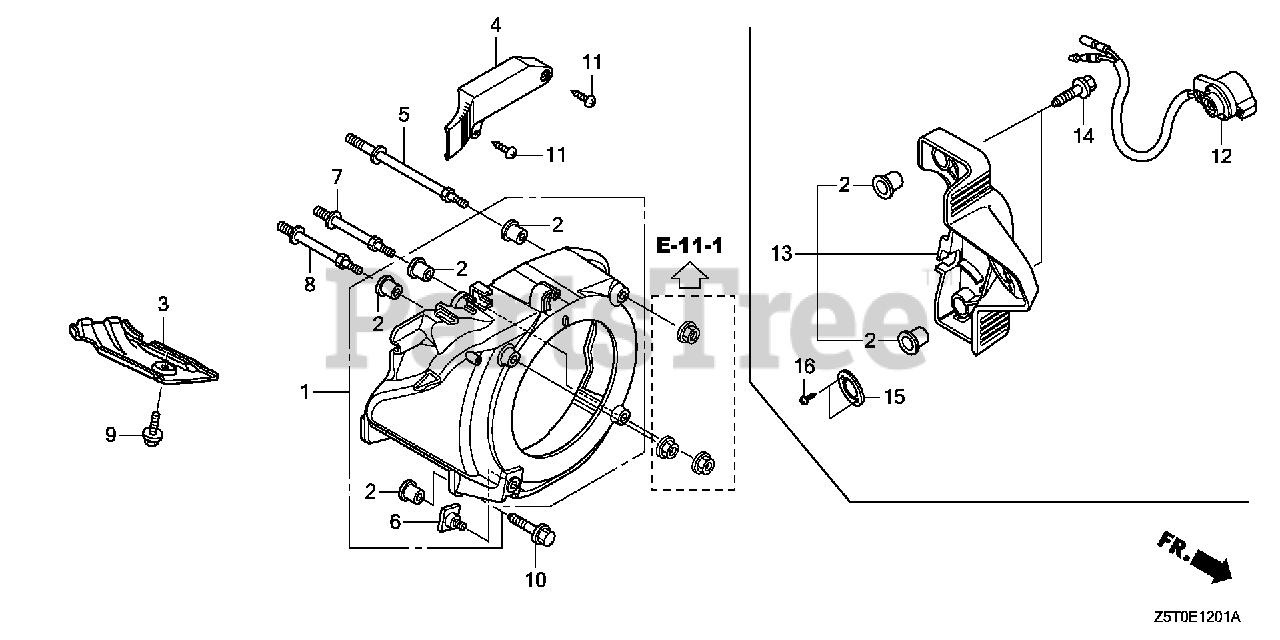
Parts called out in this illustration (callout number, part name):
1	COVER, FAN *NH1* (BLACK)
1	COVER, FAN *R280* (POWER RED)
2	COLLAR, FAN COVER
4	COVER, ELECTRONIC PARTS
5	BOLT, STUD (SEL)
6	BOLT, SPECIAL (6MM)
7	BOLT, STUD
8	BOLT B, STUD
9	BOLT, FLANGE (6X12) (CT200)
10	BOLT, FLANGE (6X25) (CT200)
11	SCREW, TAPPING (5X20)
